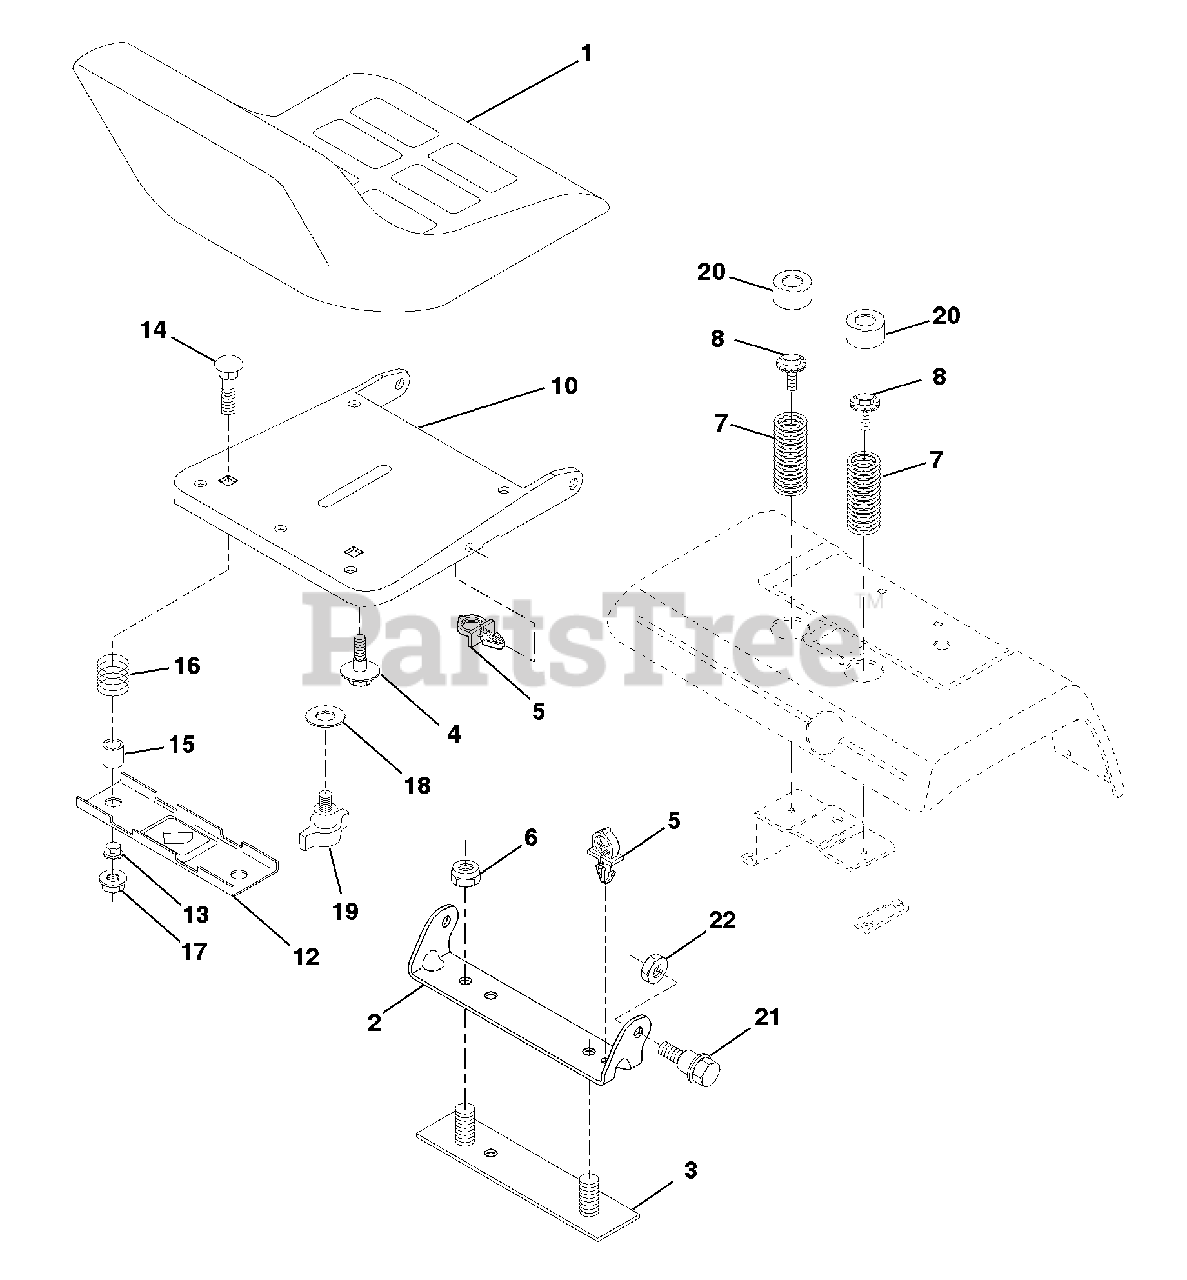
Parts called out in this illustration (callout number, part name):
1	Seat
2	Bracket, Pivot Seat
3	Strap, Fender
4	Bolt, Shoulder 5/16-18 X .62
5	Clip, Push In Hinged
6	Nut, Lock Hex W/Ins. 3/8-16 Unc
7	Spring, Seat Cprsn
8	Bolt 5/16-18unc x 3/4 W/Sems
10	Pan, Seat
12	Bracket, Mounting Switch
13	Bushing, Snap
14	Bolt, Carriage 1/4-20 X 1-1/2
15	Spacer, Split
16	Spring, Cprsn
17	Nut, Lock 1/4 Lge Flg Gr. 5
18	Washer 17/32 X 1-3/16 X 12 Ga.
19	Knob, Seat
20	Cap, Spring Seat
21	Bolt, Shoulder 5/16-18 Unc-2A
22	Nut, Crownlock 5/16-18 Unc
